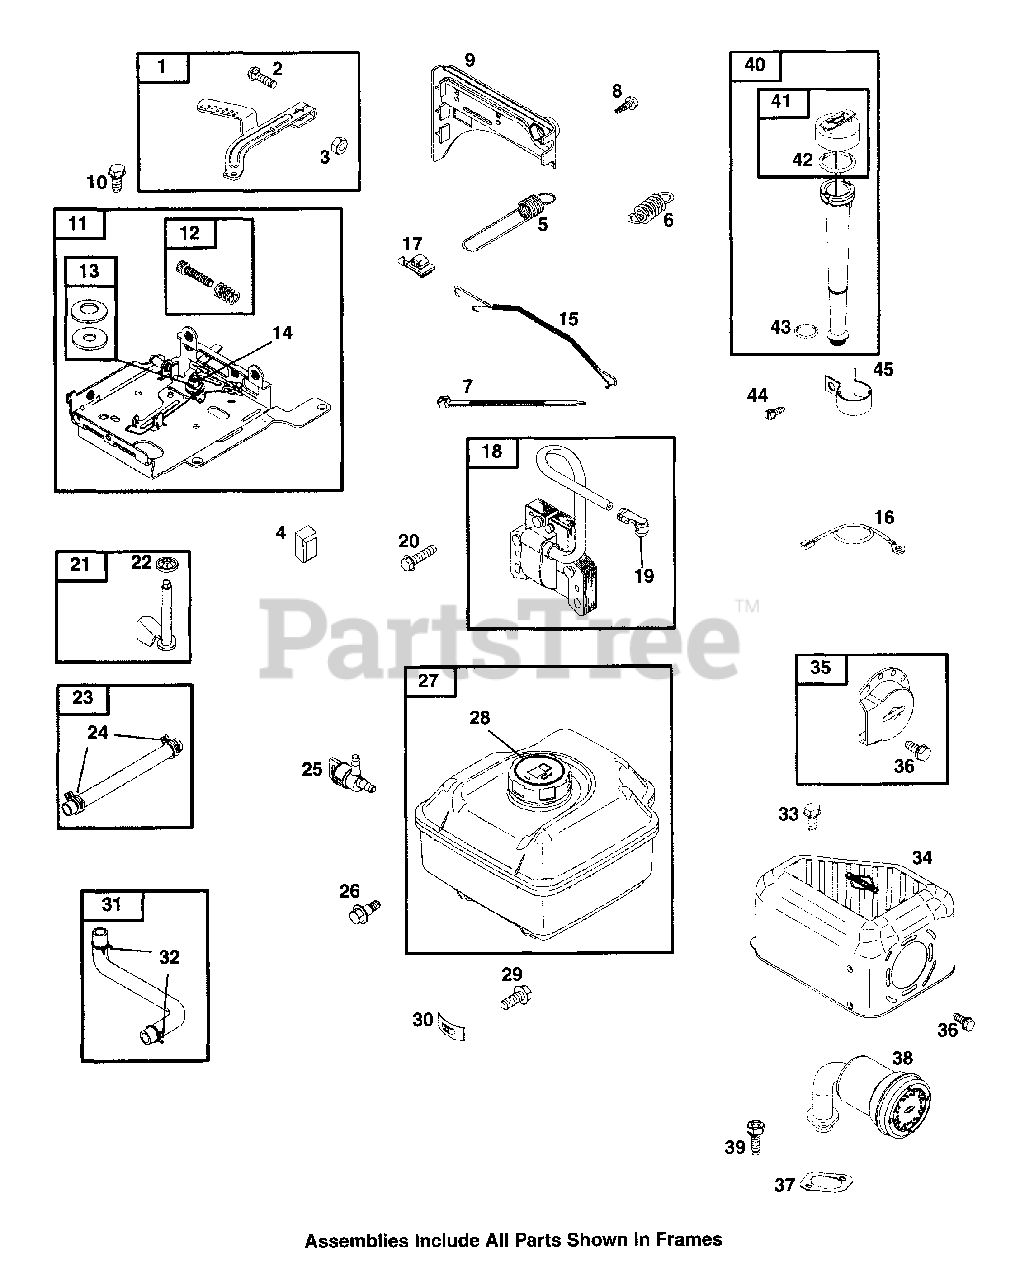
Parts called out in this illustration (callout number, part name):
1	Governor Lever
2	Bolt (Governor Control Lever)
3	Nut (Governor Control Lever)
4	Control Knob
5	Governor Spring
6	Governor Spring
8	Screw (Control Panel)
9	Control Panel
10	Screw (Control Bracket)
11	Control Bracket
12	Idle Speed Kit
13	Washer Set
14	Nut (Control Bracket)
15	Spring/Link (Mechanical Governor)
17	Switch-Stop
18	Armature-Magneto
19	Sparkplug Terminal
20	Screw (Magneto Armature)
21	Crank-Governor
22	Retainer-Governor Shaft
23	Fuel Line
24	Clamp-Hose
25	Valve-Shutoff
26	Screw (Fuel Tank)
27	Fuel Tank
28	Fuel Tank Cap
29	Screw (Fuel Tank)
31	Fuel Line (Molded)
32	Clamp-Hose
33	Screw (Muffler Guard)
34	Guard-Muffler
35	Deflector-Muffler
36	Screw (Muffler Deflector)
37	Gasket-Exhaust
38	Muffler-Exhaust
39	Screw (Muffler)
40	Dipstick/Tube Assembly
42	O-Ring Seal (Dipstick)
43	O-Ring Seal
44	Screw (Oil Fill Bracket)
45	Oil Fill Bracket
